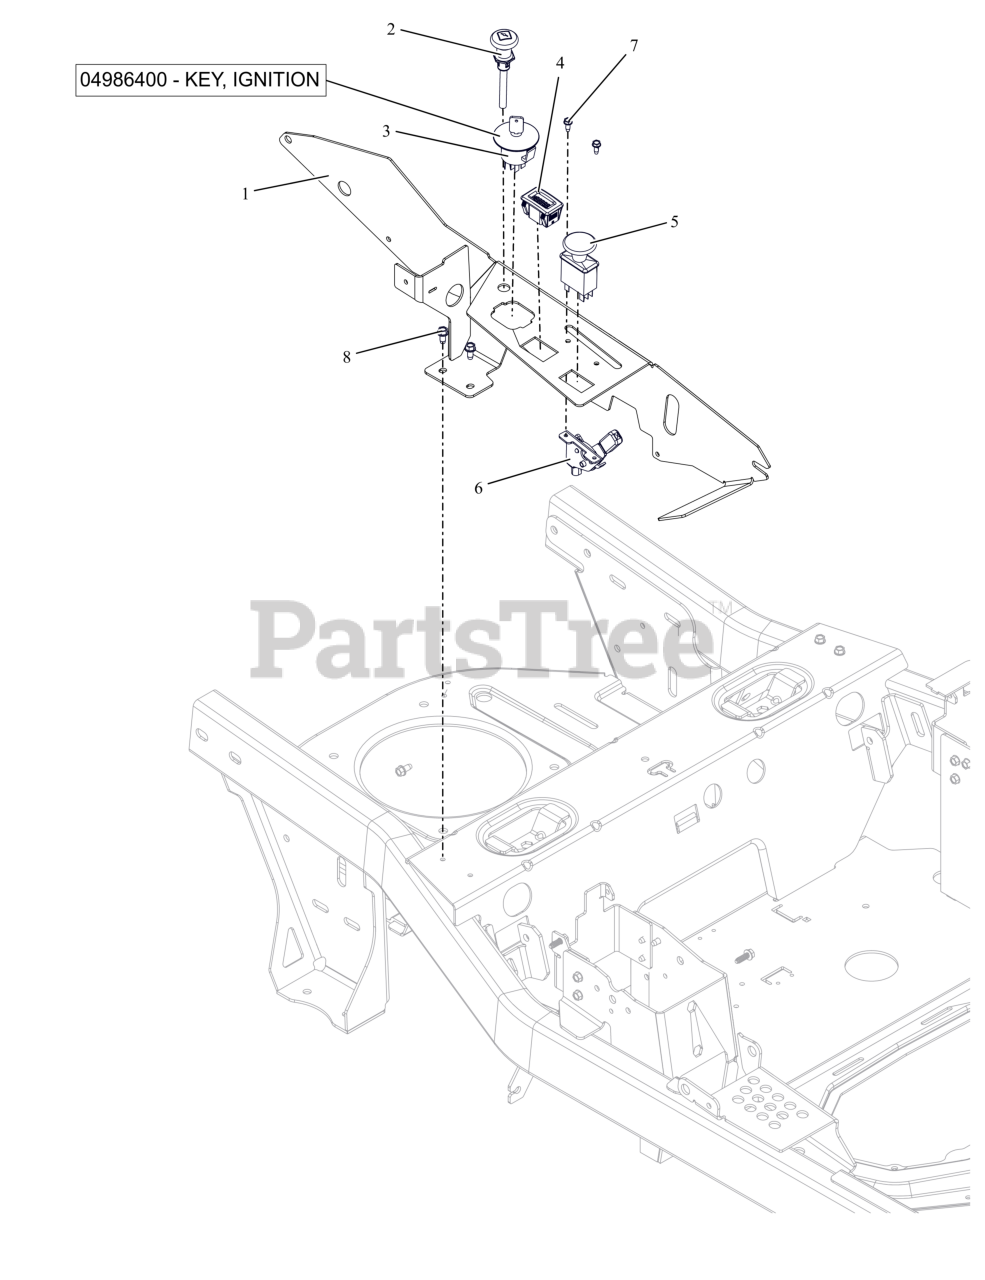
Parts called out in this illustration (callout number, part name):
1	PANEL- CONTROL-RH-GRAVELY
2	CABLE- CHOKE-SNAP IN 37"
3	KEYSWITCH-IGNITION 4 POS
3	KEY, IGNITION
4	HOUR METER
5	SWITCH, CLUTCH
6	CABLE- THROTTLE
7	SCR,TAP #10-24X.50 HWH TR ZCC
8	SCR-TAP .25-20X.50 HWH ZCC
